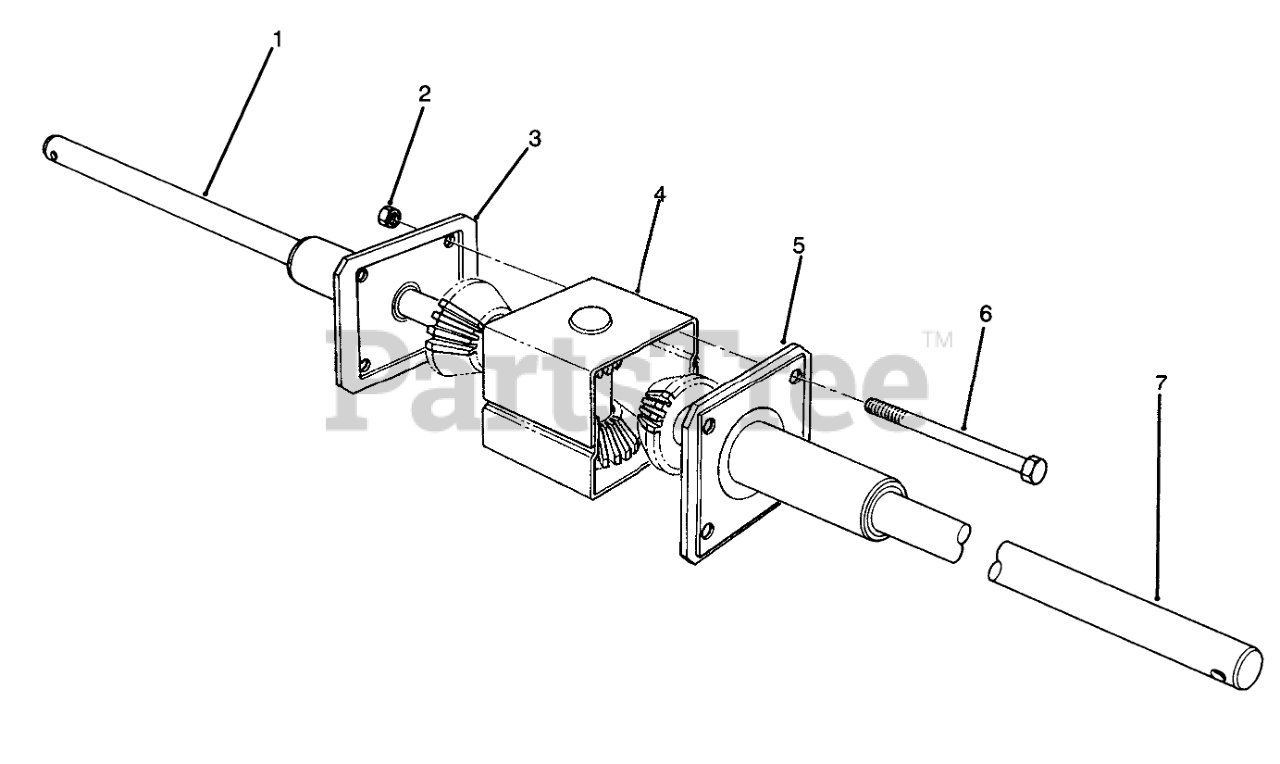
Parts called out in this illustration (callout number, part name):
2	NUT-LOCK, CONE
3	END CAP/BRG ASM
4	GEAR CASE ASM
5	END CAP &BEARING ASY
6	SCREW-HH
